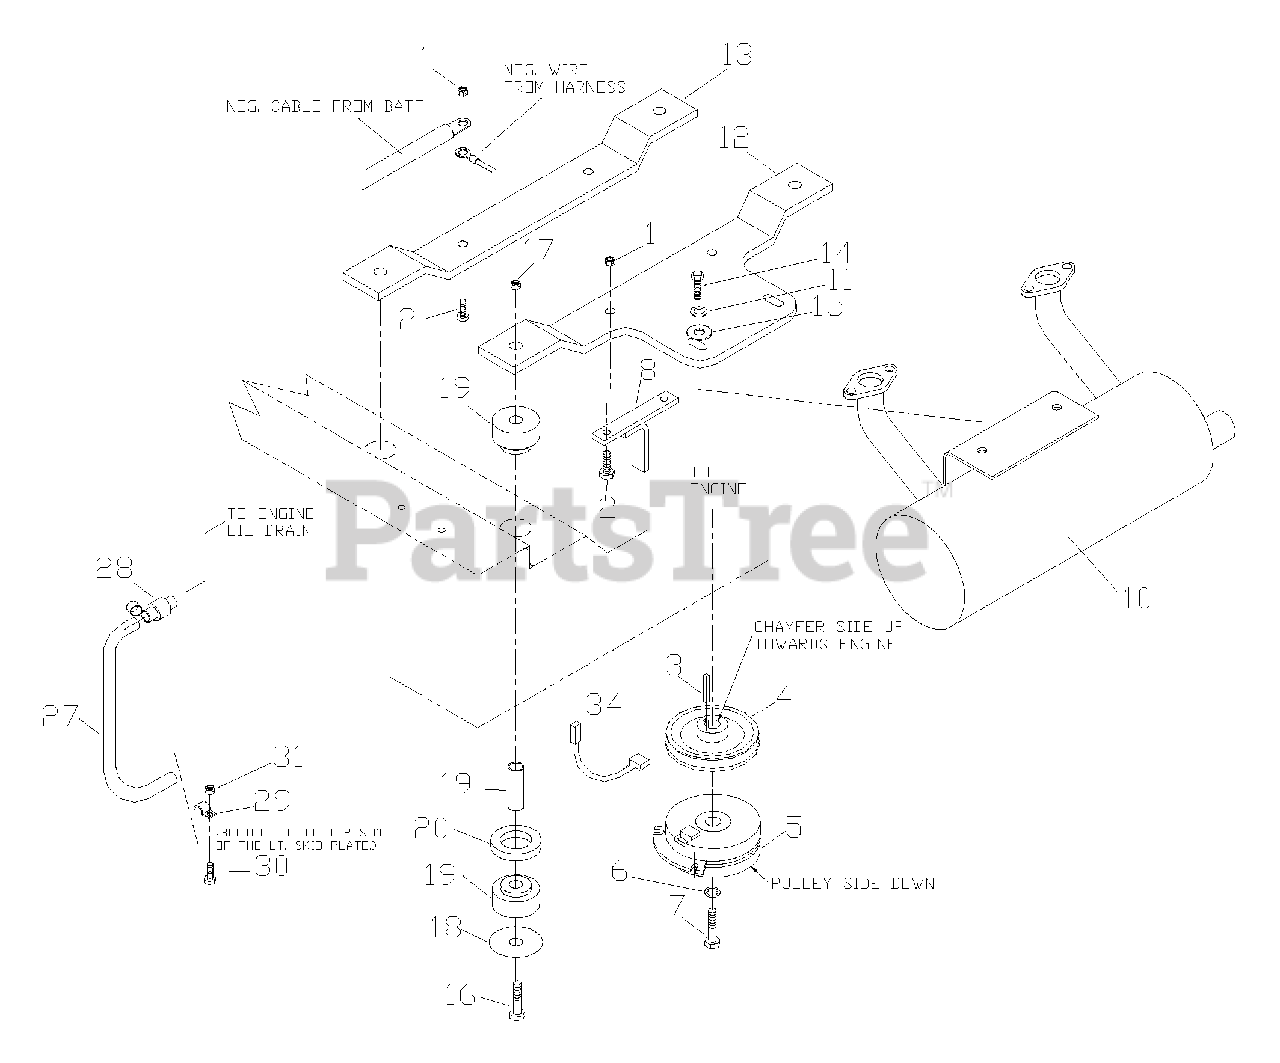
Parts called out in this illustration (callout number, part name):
1	NUT 5/16 LOCK
2	HCS 5/16 X 1.75
3	KEY 1/4 SQ
6	WASHER 7/16 LOCK
7	HCS 7/16F X 2.5
8	CLUTCH TIE DOWN
11	WASHER 5/16 LOCK
12	ENGINE MOUNT
13	ENGINE MOUNT
14	HCS 5/16 X 750
15	WASHER 5/16 FLAT
16	HCS 1/2 X 3.25
17	NUT 1/2 NYLOC
27	OIL DRAIN HOSE
28	OIL DRAIN FITTING
30	HCS 1/4 X 750
31	NUT 1/4 CTR LOCK
34	CLUTCH PIGTAIL
